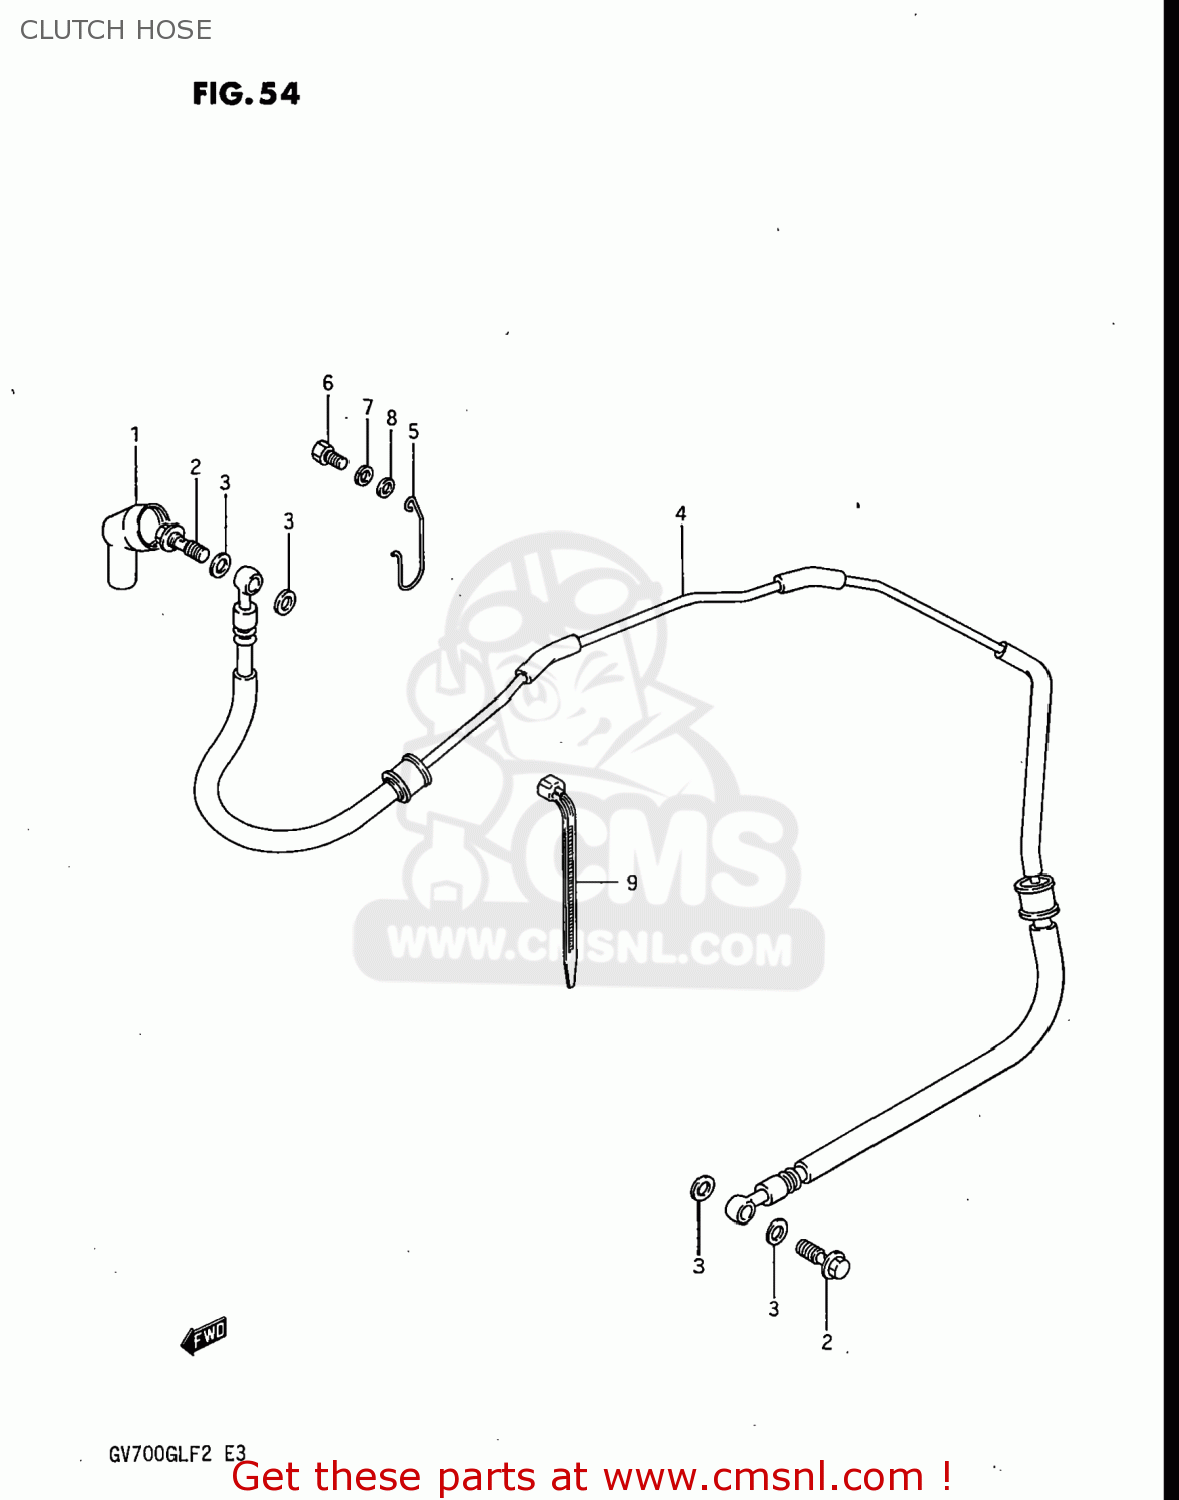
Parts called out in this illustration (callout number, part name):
1	BOOT,MASTER CYLINDER
2	BOLT UNION
3	WASHER(10X15X1.5)
4	HOSE,CLUTCH
5	GUIDE,CLUTCH HOSE
6	BOLT
7	LOCK WASHER
8	WASHER
9	CLAMP(L:165)
